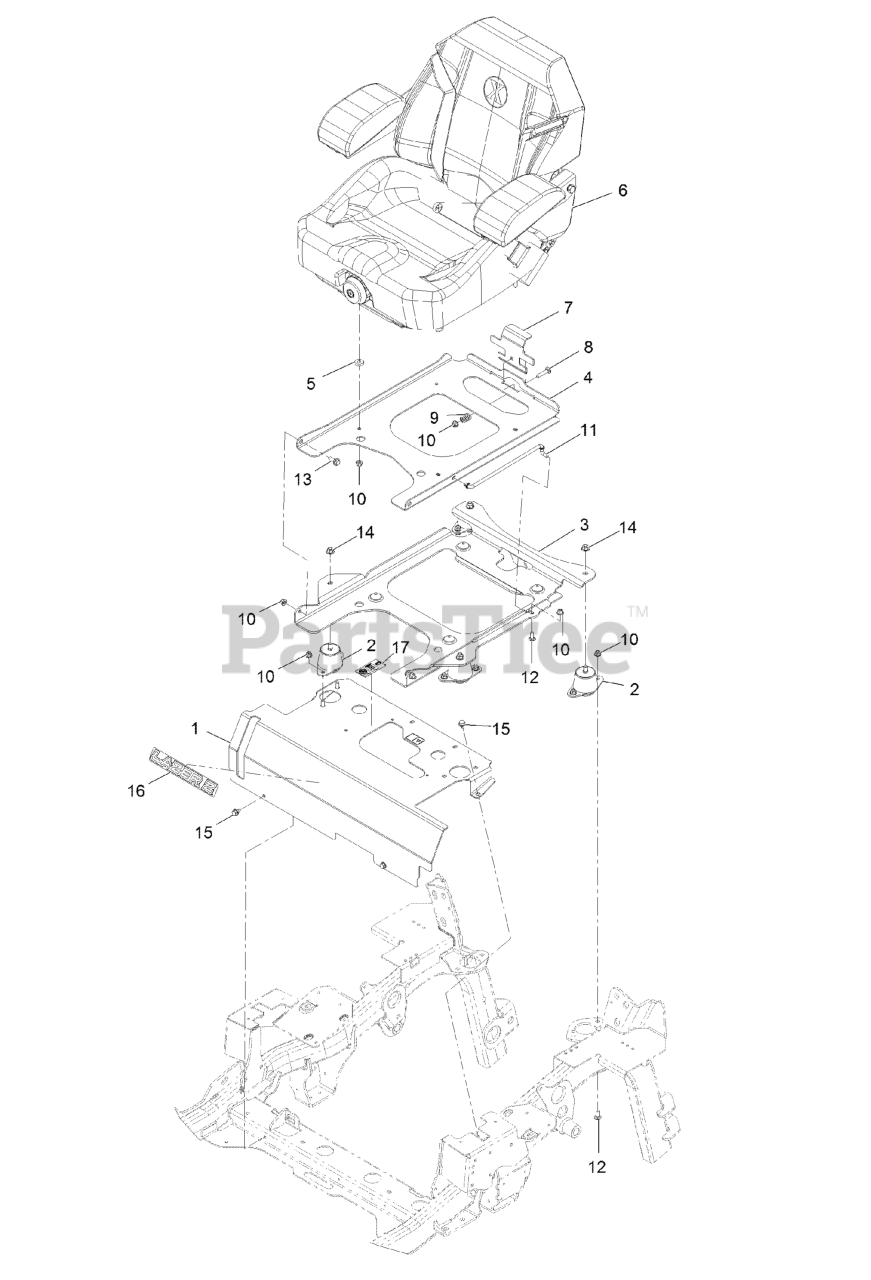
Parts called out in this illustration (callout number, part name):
1	SEAT MOUNT ASM
2	ISOLATOR-SEAT
3	PLATE-SUPPORT, TILT SEAT
4	PLATE-FRAME, SEAT
6	KIT-SUSPENSION SEAT
7	PLATE, SEAT LATCH
8	BOLT-CARR
9	SPRING-COMPRESSION
10	NUT-HF, NI
11	ROD-PROP
12	SCREW-CARR
13	SCREW-SHOULDER
14	NUT-HF, NI
16	DECAL, LAZER MODEL
17	DECAL-TRANS FLUID
